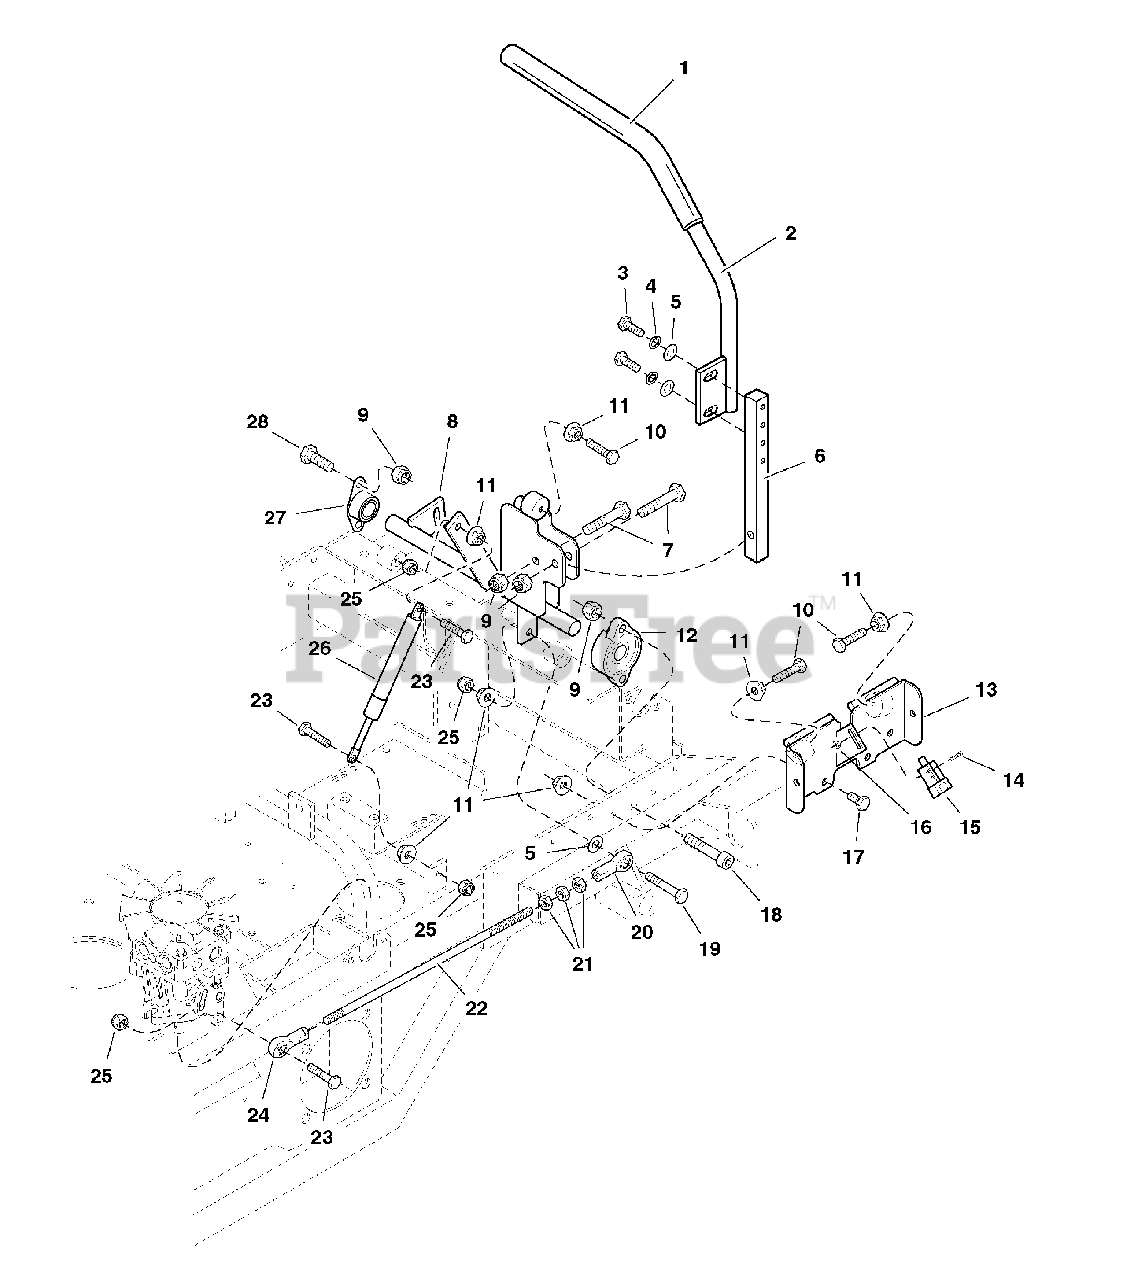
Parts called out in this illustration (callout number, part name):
2	MOTION CONTROL LEVER-RH
3	CAPSCREW, Hex Hd, 5/16-18 x 3/4
4	WASHER, Lock, 5/16
5	WASHER, 5/16
6	MOUNT, CONTROL ARM - BLK
7	CAPSCREW, Hex Hd, 3/8-16 x 1-3/4
8	CONTROL SHAFT-RH
9	NUT, Hex, Nylon Lock, 3/8-16
10	CAPSCREW, Hex Hd, 5/16-18 x 1-3/4
11	NUT, Hex, Serrated Flange, 5/16-18
12	BEARING, Flange
13	NEUTRAL LOCK BRACKET-RH
14	SCREW, #10-24 x 1
15	SWITCH, PLUNGER, N.O./N.C.
16	NUT, Hex, #10-24
17	CAPSCREW, Hex Hd, 5/16-18 x 1
18	CAPSCREW, Allen Hd, 3/8-16 x 1-1/4
19	CAPSCREW, Hex Hd, 5/16-18 x 1-3/4
20	BALL JOINT 5/16-24 RH FEMALE STAMPED STL
21	NUT, Hex, 5/16-24
22	HYDRO CONTROL ROD
23	CAPSCREW, Hex Hd, 5/16-18 x 1-1/4
24	BALL JOINT 5/16-24 LH FEMALE STAMPED STL
25	NUT, Hex, Nylon Lock, 5/16-18
26	DAMPENER
27	BEARING, Flange
28	CAPSCREW, Hex Hd, 3/8-16 x 1
